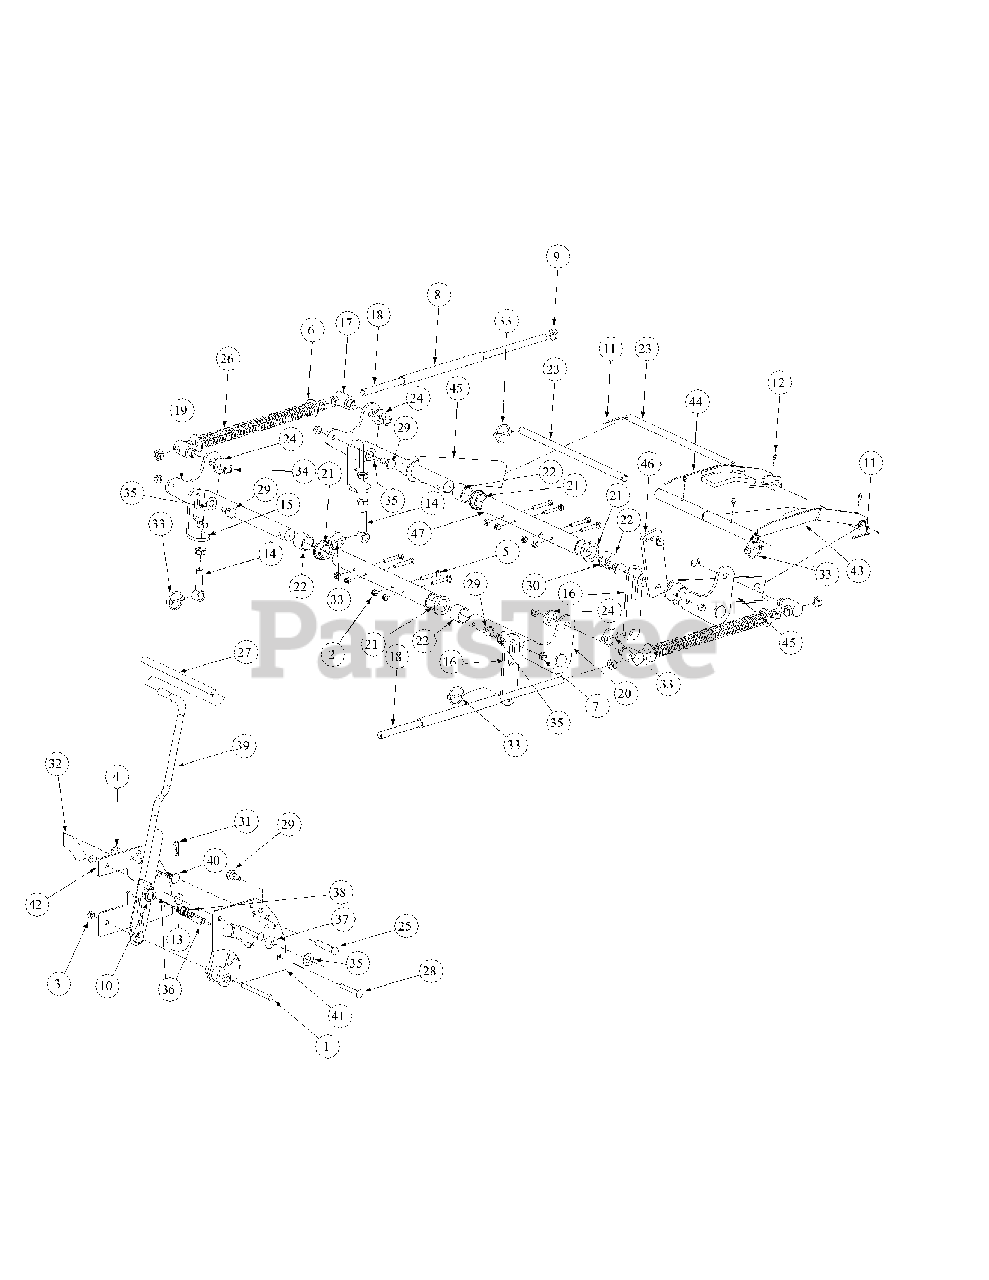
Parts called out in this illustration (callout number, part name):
1	Hex Cap Screw, 3/8-16, 3.75
2	Nut, 5/16-18, Nylock
3	Nylock Insert Lock Nut, 3/8-16
4	Nylock Insert Lock Nut, 1/2-13
5	Hex Cap Screw, 5/16-18 x 2
6	Flat Washer, 5/8
7	Hex Nut, Flange Lock, 3/8-16
8	Hose, 5/8 ID 13/16 OD, 8" LG
9	Jam Nut, 5/8-11
10	Flat Washer, .06, .776, 1.25
11	Cotter Pin, 3/16 x 1-1
12	Grease Fitting, 1/4-28 x 3/16
13	Idler Washer
14	Eye Bolt, 5/8ID
15	Eye Bolt Mount Link, 5/8 ID
16	Deck Link
17	Ferule Lift
18	Lift Connector Rod
19	Bellecrank Weldment Lift, Left Hand
20	Bellecrank Weldment Lift, Right Hand
21	Hex Flange Bearing, 1.25 ID
22	Frame Lift Spacer
23	Front Lift Link, Rod Mount
24	Spacer, .812 ID x .268 Lg.
25	Clevis Pin, .500 Dia. x 2.625 Lg.
26	Lift Compression Spring
27	Lift Handle Grip
28	Carriage Bolt, 3/8-16, 2.75
29	Shoulder Screw, 0.625 OD x .437 Lg.
30	Shoulder Screw, 0.625 OD x .830 Lg.
31	Cotter Pin, .148 x 3.00
32	Decal Height Indicator
33	Linch Pin, 3/16 Dia.
34	E Clip, 3/4 Dia.
35	Nylon Flat Washer, 5/8
36	Spacer, .39 ID x .63 OD x 1.442
37	Lift Pivot Assembly
38	Lift Handle Spring
39	Lift Handle Assembly
40	Shoulder Screw, 5/8 OD x 0.264
41	Outer Lift Index Plate
42	Inner Lift Index Plate
43	Bearing Lift Brace Assembly, Right Hand
44	Bearing Lift Brace Assembly, Left Hand
45	Front Frame Strut Assembly
46	Lift Link Adjustment
47	Lift Shaft Holder
